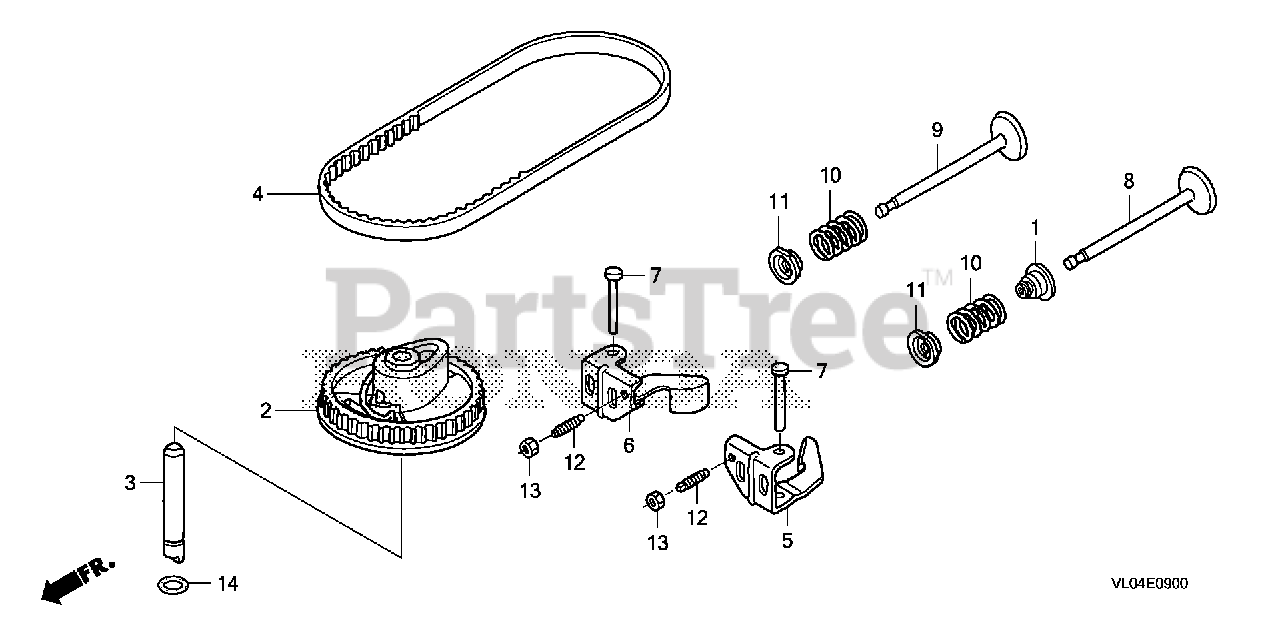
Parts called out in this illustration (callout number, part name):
1	SEAL, VALVE STEM
2	PULLEY, CAMSHAFT
3	SHAFT, CAM PULLEY
4	BELT, TIMING (84HU6 G-200)
5	ARM, IN. VALVE ROCKER
6	ARM, EX. VALVE ROCKER
7	SHAFT, ROCKER ARM
8	VALVE, IN.
8	VALVE, IN. (TECHNOSTAR)
9	VALVE, EX. (L8E)
9	VALVE, EX. (C8E)
10	SPRING, VALVE
11	RETAINER, VALVE SPRING
12	SCREW, TAPPET ADJUSTING
13	NUT, TAPPET ADJUSTING
14	O-RING (6.8X1.9) (ARAI)
